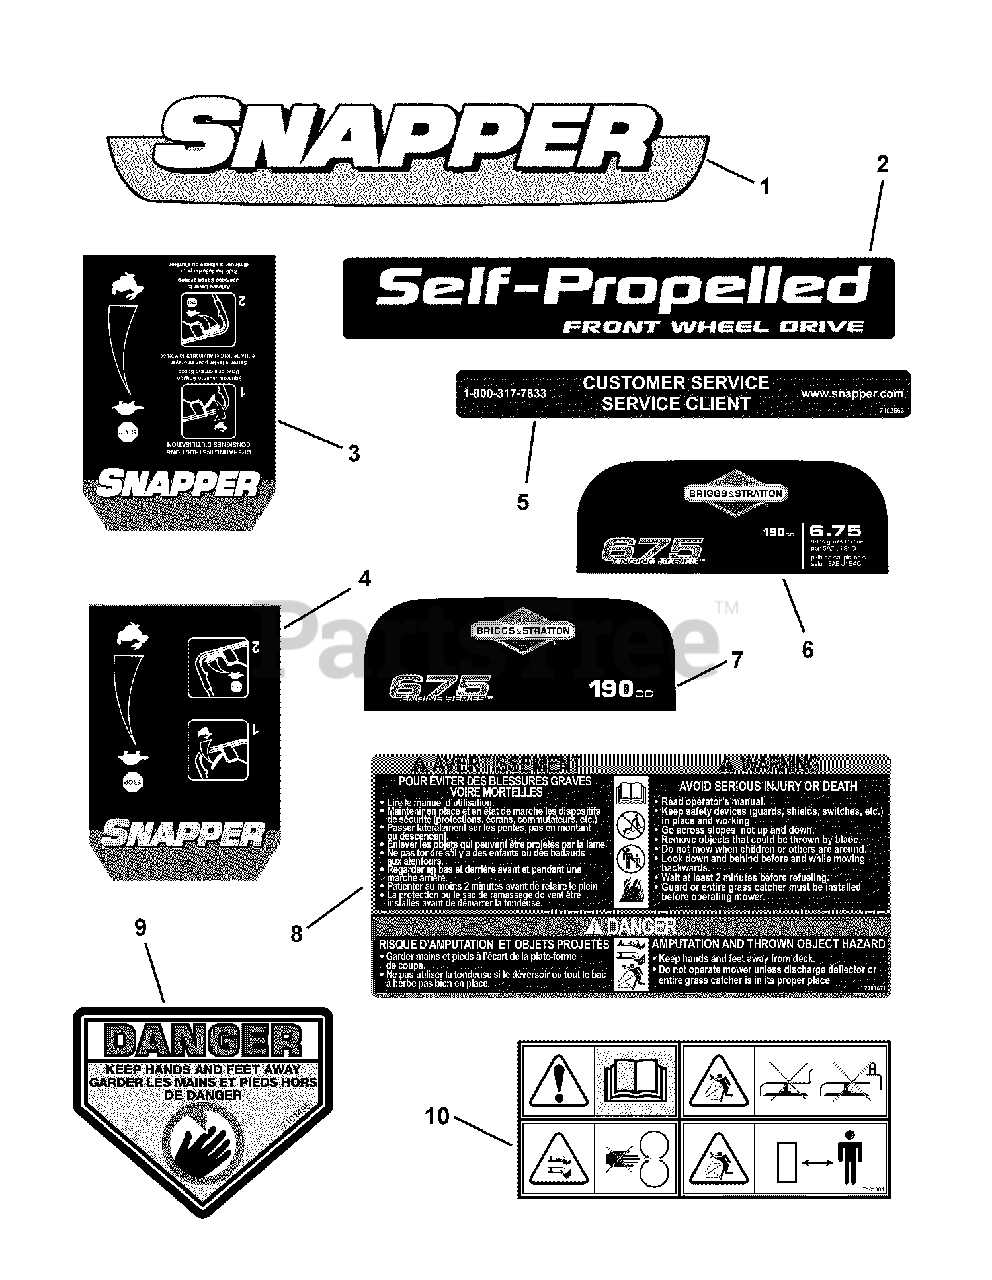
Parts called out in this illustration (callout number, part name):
1	DECAL, Briggs Engine, Snapper
2	DECAL, Front Cover, 22" Snapper, FWD
3	DECAL, Control Head, VS, Snapper, FC
4	DECAL, Control Head, VS, Snapper, Euro
5	DECAL, Customer Service
7	DECAL, Engine, TP, 675, Snapper, Euro
8	DECAL, WB Safety, French/English
9	DECAL, CPSC, French/English
10	DECAL, Warning, Eurp Multi-Panel
